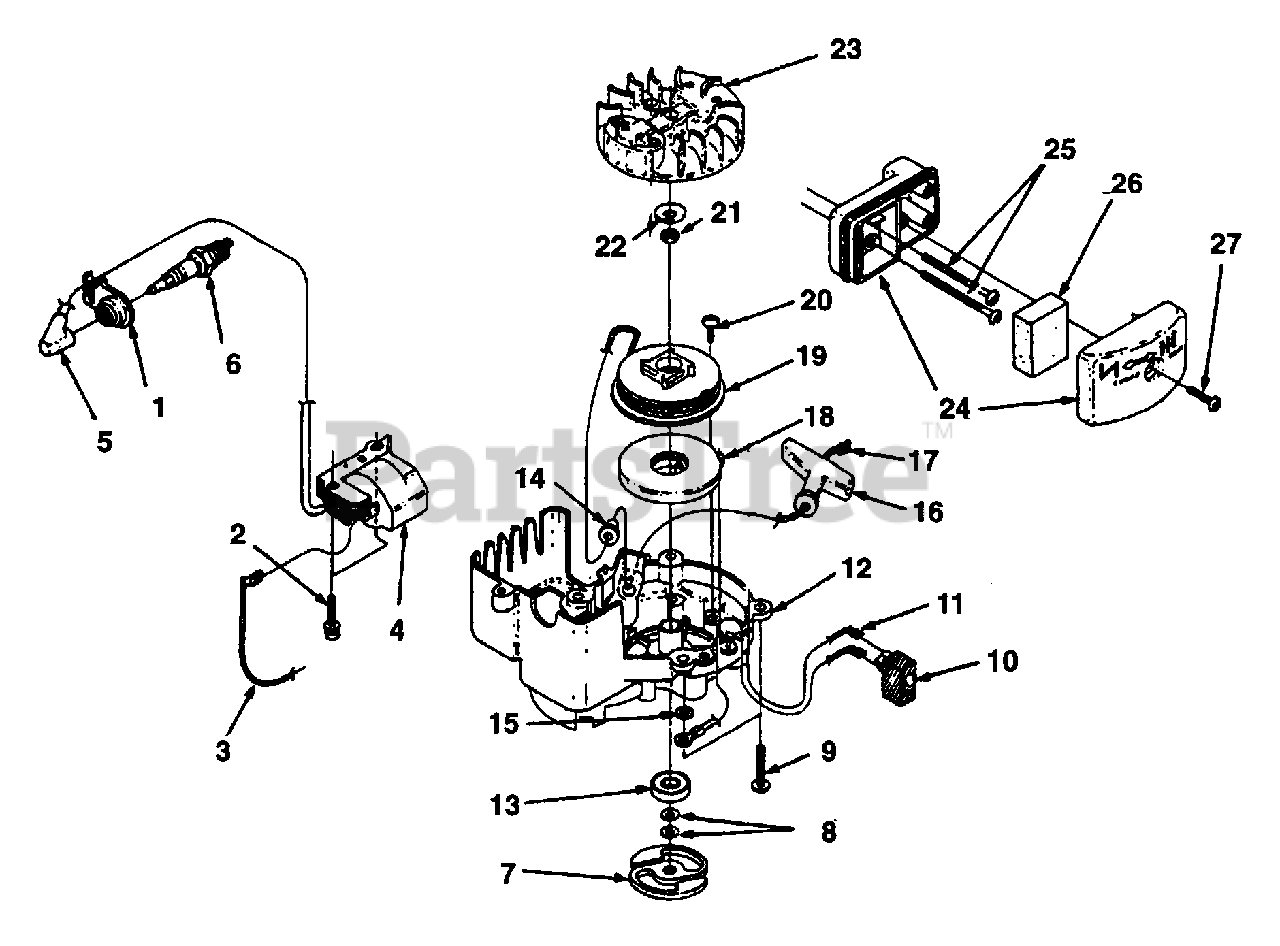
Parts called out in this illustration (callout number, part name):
1	SHIELD-Spark Plug
2	SCREW-Thread Form. (8-32 x 1")
3	LEAD-Electrical
4	MODULE-Ignition
5	SPARK PLUG BOOT KIT
6	SPARK PLUG (RDY-7Y)
7	CLUTCH "S"
8	WASHER-Belleville
9	SCREW-Taptite (10-24 x 3/4")
10	SWITCH
11	SWITCH
11	LEAD-Ground
12	HOUSING-Engine & Pulley
13	BEARING-Ball
14	BUSHING-Starter
15	WASHER-Flat (#10)
16	GRIP-Starter Rope
17	ROPE-Starter (42")
18	SPRING & CONTAINER
19	PULLEY-Starter
20	SCREW-Thread Form. (#10 x 1/2")
21	NUT-Hex (7/16-20)
22	WASHER-Conical
23	ROTOR
24	AIR FILTER HOUSING
25	SCREW-Machine (10-24 x 2 1/4")
26	FILTER-Air
27	SCREW-Thread Form. (#8 x .750)
